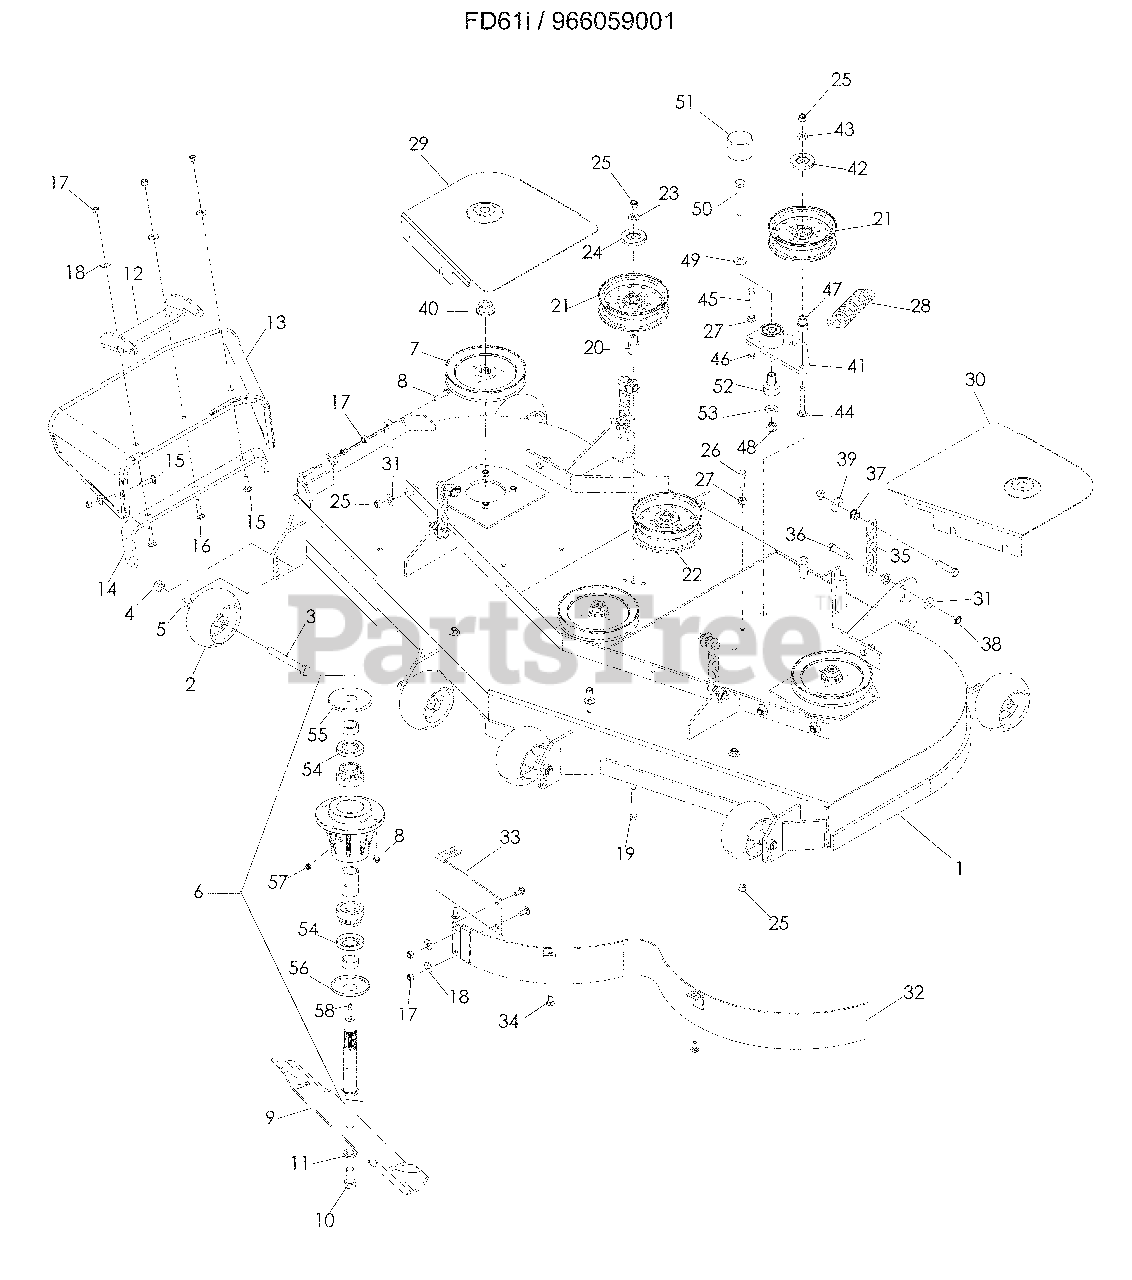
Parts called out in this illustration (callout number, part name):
1	DECK w/ DECALS
2	WHEEL, GAUGE
3	HCS ½-13 x 4
4	NUT ½ NYLOC
6	HOUSING, 52/61
7	PULLEY, 61
8	HCS 5/16-18 x 1¼
9	BLADE, 21"
10	HCS 5/8-18 x 1¼
11	LOCKWASHER 5/8
12	PIVOT BRACKET, CHUTE
13	RUBBER CHUTE 52/61
14	REINFORCEMENT, BRACKT
15	RHSNB 5/16-18 x 1¼
16	RHSNB 5/16-18 x 1½
17	NUT 5/16-18 NYLOC
18	WASHER 5/16
19	HCS 3/8-16 x 2¾
20	IDLER BUSHING
21	IDLER PULLEY
22	IDLER PULLEY
23	WASHER 3/8 THICK
24	SHIELD, DUST
25	NUT 3/8-16 NYLOC
26	HCS 3/8-16 x 1¼
27	NUT 3/8-16 WHIZLK
29	BELTSHIELD, RIGHT
30	BELTSHIELD, LEFT
31	WASHER 3/8
32	MAIN WELDMENT
33	CENTER BAFFLE
34	RHSNB 5/16-18 x ¾
35	LIFT CHAIN
36	HCS 7/16-14 x 1¾
37	NUT 7/16-14 WHIZLK
38	NUT 7/16-14 NYLOC
39	WASHER 7/16
40	NUT ¾-16 FLANGE
41	ARM w/ BEARINGS, IDLER
42	SHIELD, DUST
43	WASHER 3/8 THICK
44	RHSNB 3/8-16 x 2¾
45	HCS 3/8-16 x 1½ GR8
46	NUT 3/8-16 JAM
47	BUSHING, IDLER
48	NUT ½ NYLOC
49	WASHER ½ BELLEVILLE
50	HCS ½-13 x 3
51	CAP, VINYL
52	PIVOT, BEARING
53	WASHER ½ SAE
54	SHAFT SEAL
55	DUST CAP, TOP
56	DUST CAP, BOTTOM
57	GREASE POPPET
